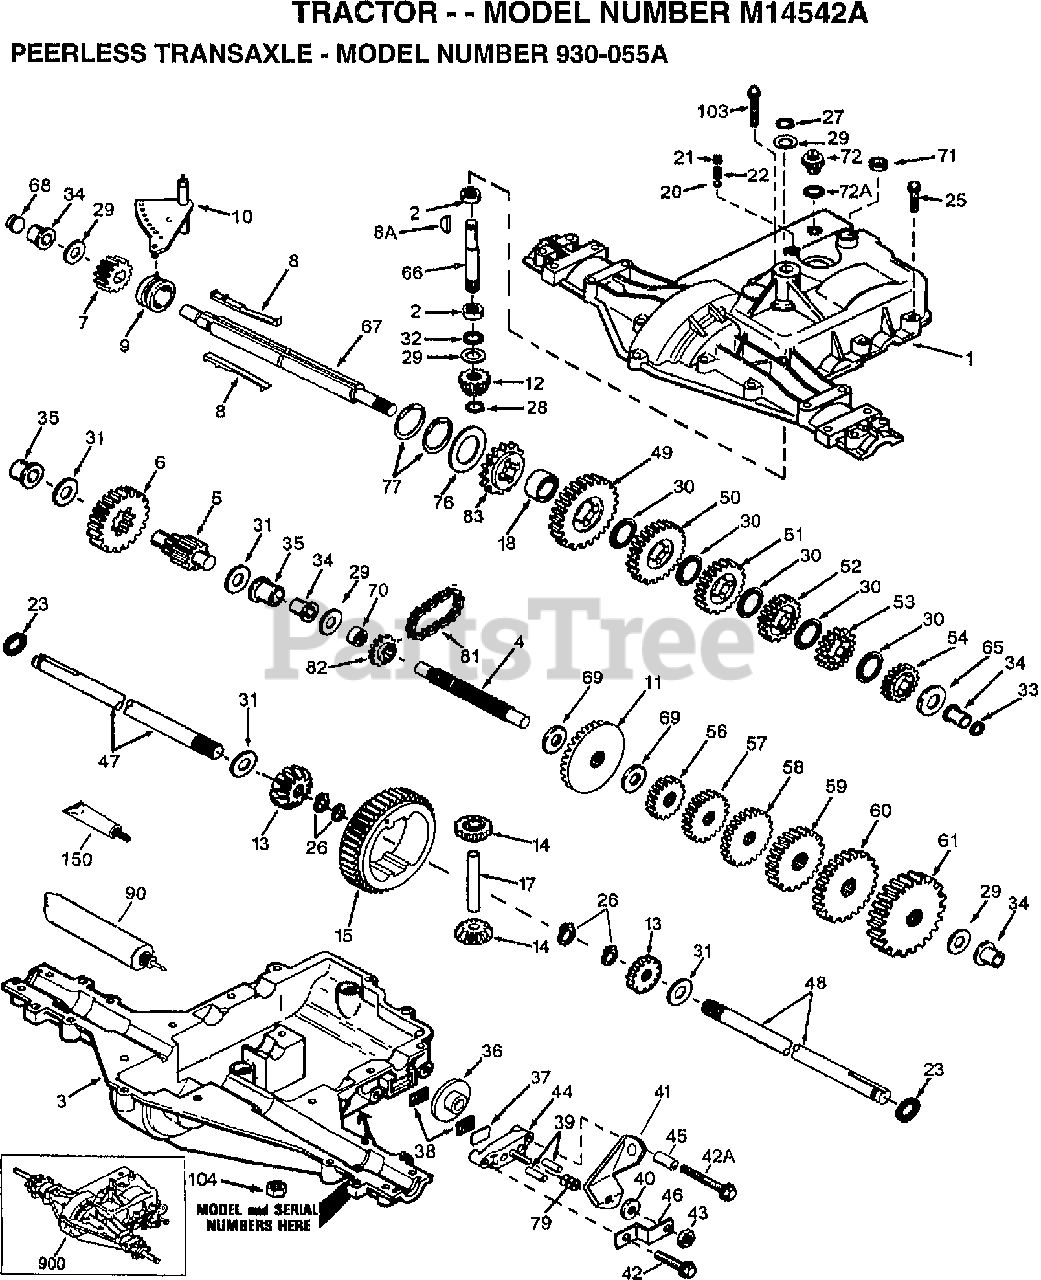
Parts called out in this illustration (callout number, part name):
1	TRANSAXLE COVER
2	BEARING, NEEDLE
3	TRANSAXLE CASE
4	SHAFT, COUNTER
5	OUTPUT SHAFT AND PINION
6	GEAR, OUTPUT
7	GEAR, SPUR, 15 TEETH
8A	KEY, WOODRUFF
9	COLLAR, SHIFTER
10	ROD & FORK ASSY, SHIFT
11	GEAR, BEVEL, 42 TEETH
12	BEVEL PINION, INPUT
13	GEAR, BEVEL
14	GEAR, BEVEL, PINION
18	SPACER, NEUTRAL
20	BALL STEEL, 5/16" DIA.
21	SCREW, 3/8-16 X 3/8"
25	SCREW, 1/4-20 X 1-1/4
26	RING RETAINER
27	RING, RETAINER
28	RETAINING RING
29	WASHER THRUST
30	WASHER THRUST
33	SEAL, SQUARE CUT
34	BUSHING, FLANGED
35	BUSHING, FLANGED
36	DISK, BRAKE
37	PLATE BRAKE PAD
41	BRAKE LEVER
42	SCREW, 1/4-20 X 1-1/4
42A	SCREW, 1/4-20 X 2-1/4
43	LOCKNUT 5/16-24
44	HOLDER BRAKE PAD
46	BRKT BRAKE LEVER
49	GEAR, SPUR, 37 TEETH
50	GEAR, SPUR, 35 TEETH
51	GEAR, SPUR, 30 TEETH
52	GEAR, SPUR, 25 TEETH
53	GEAR, SPUR, 22 TEETH
54	GEAR, SPUR, 19T
56	GEAR, SPUR, 12 TEETH
57	GEAR, SPUR, 15 TEETH
58	GEAR, SPUR, 20 TEETH
59	GEAR, SPUR, 25 TEETH
60	GEAR, SPUR, 28 TEETH
61	GEAR, SPUR, 31 TEETH
65	WASHER, THRUST
66	SHAFT, INPUT
67	SHAFT, BRAKE, 4 KEYED
69	WASHER THRUST
71	SEAL SQUARE CUT
72	THREADED PLUG 9/16-18
76	WASHER, THRUST
77	INVERTED RETAINING RING
81	CHAIN, ROLLER
82	SPROCKET 9T
83	SPROCKET 18T (REV)
90	GREASE BENTONITE, 32 OZ.
150	GASKET ELIMINATOR
900	REPLACEMENT TRANSAXLE
